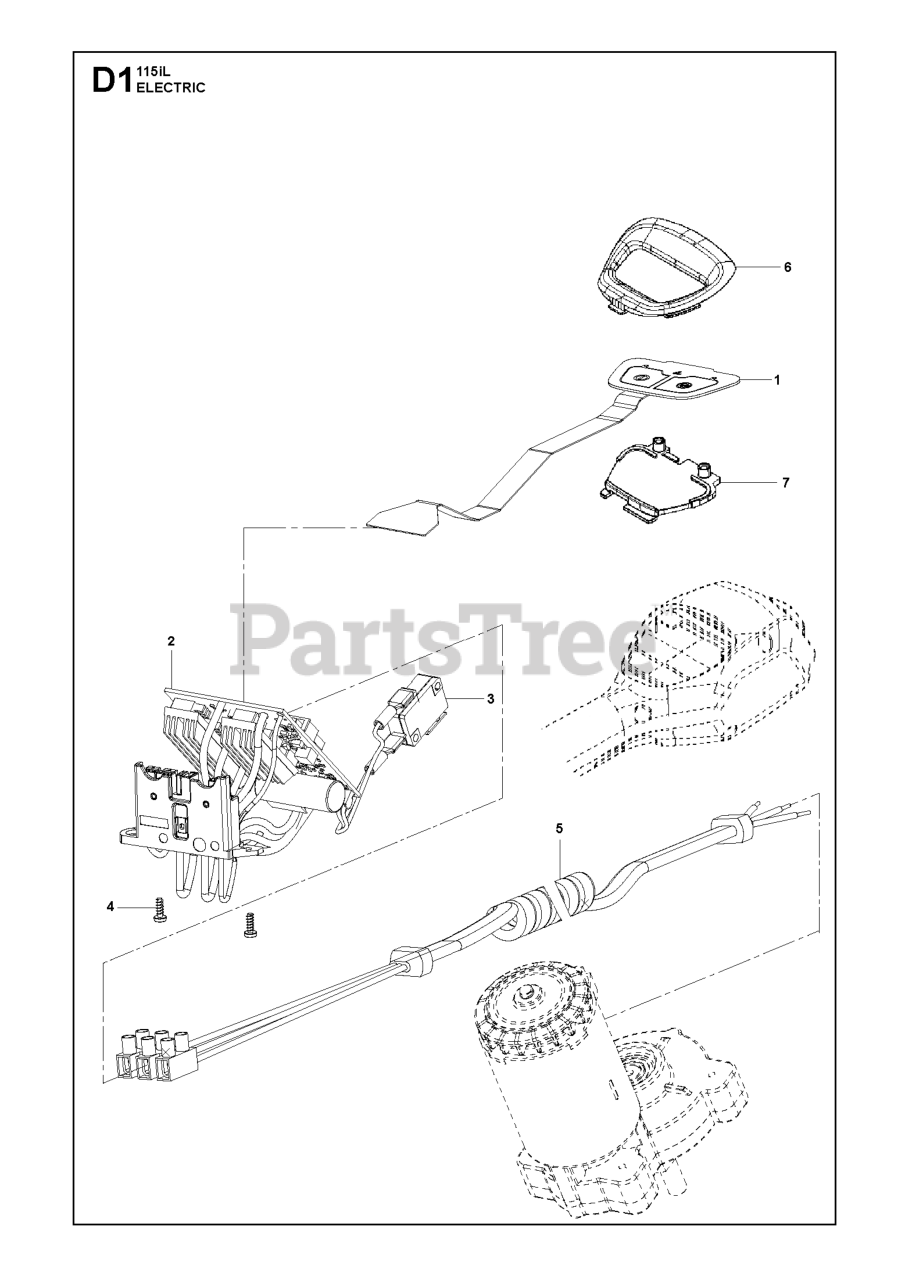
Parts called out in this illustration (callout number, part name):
1	KEYPAD TRIMMER 36V
2	CONTROL UNIT
4	SCREW ST3X8
6	PANEL KEYPAD
7	SUPPORT KEYPAD PANEL
